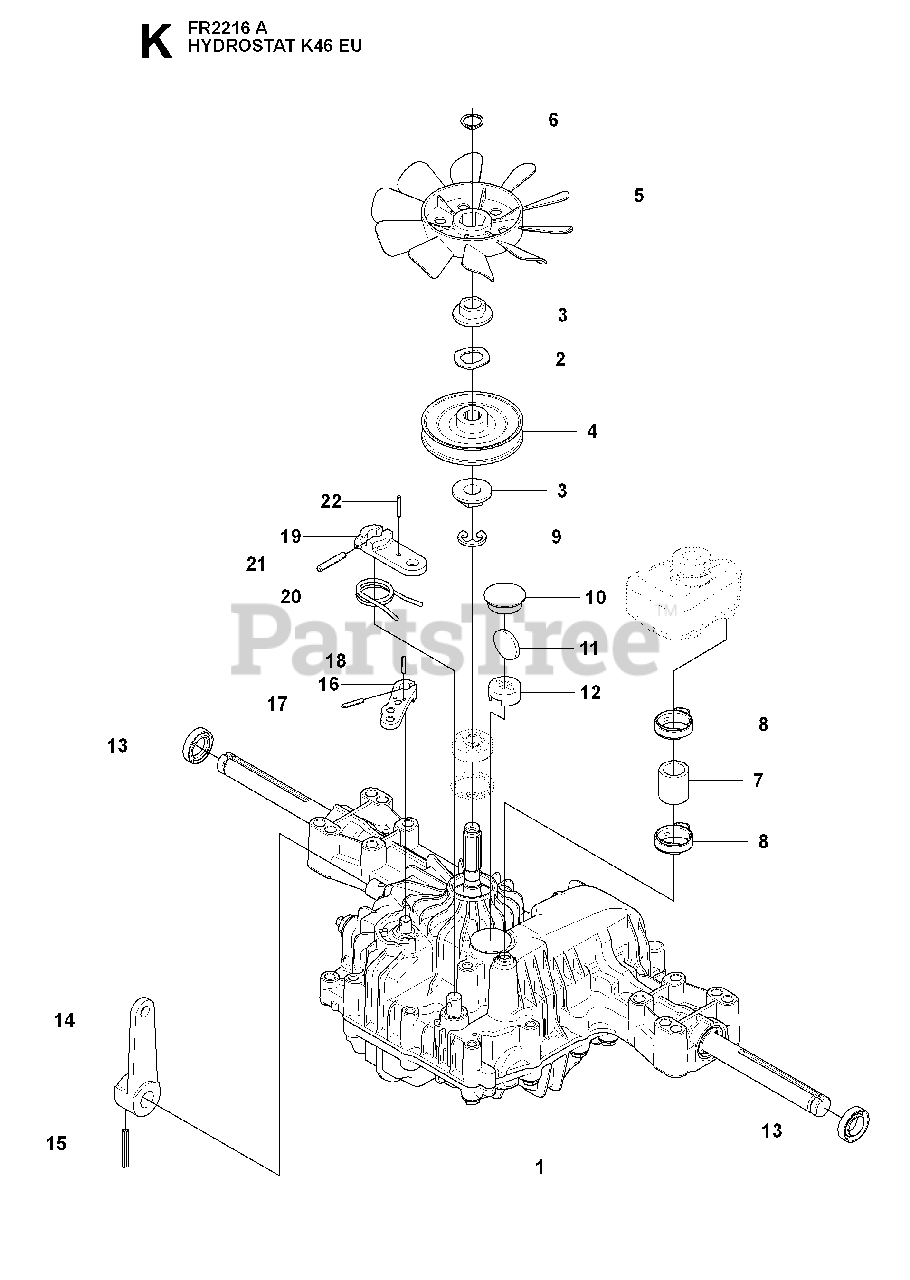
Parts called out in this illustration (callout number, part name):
1	HYDROSTAT
2	WASHER **
5	FAN
6	RETAINING RING **
8	CLAMP
12	MAGNET HOLDER
13	SEALING
14	CONTROL LEVER
20	RETURN SPRING
